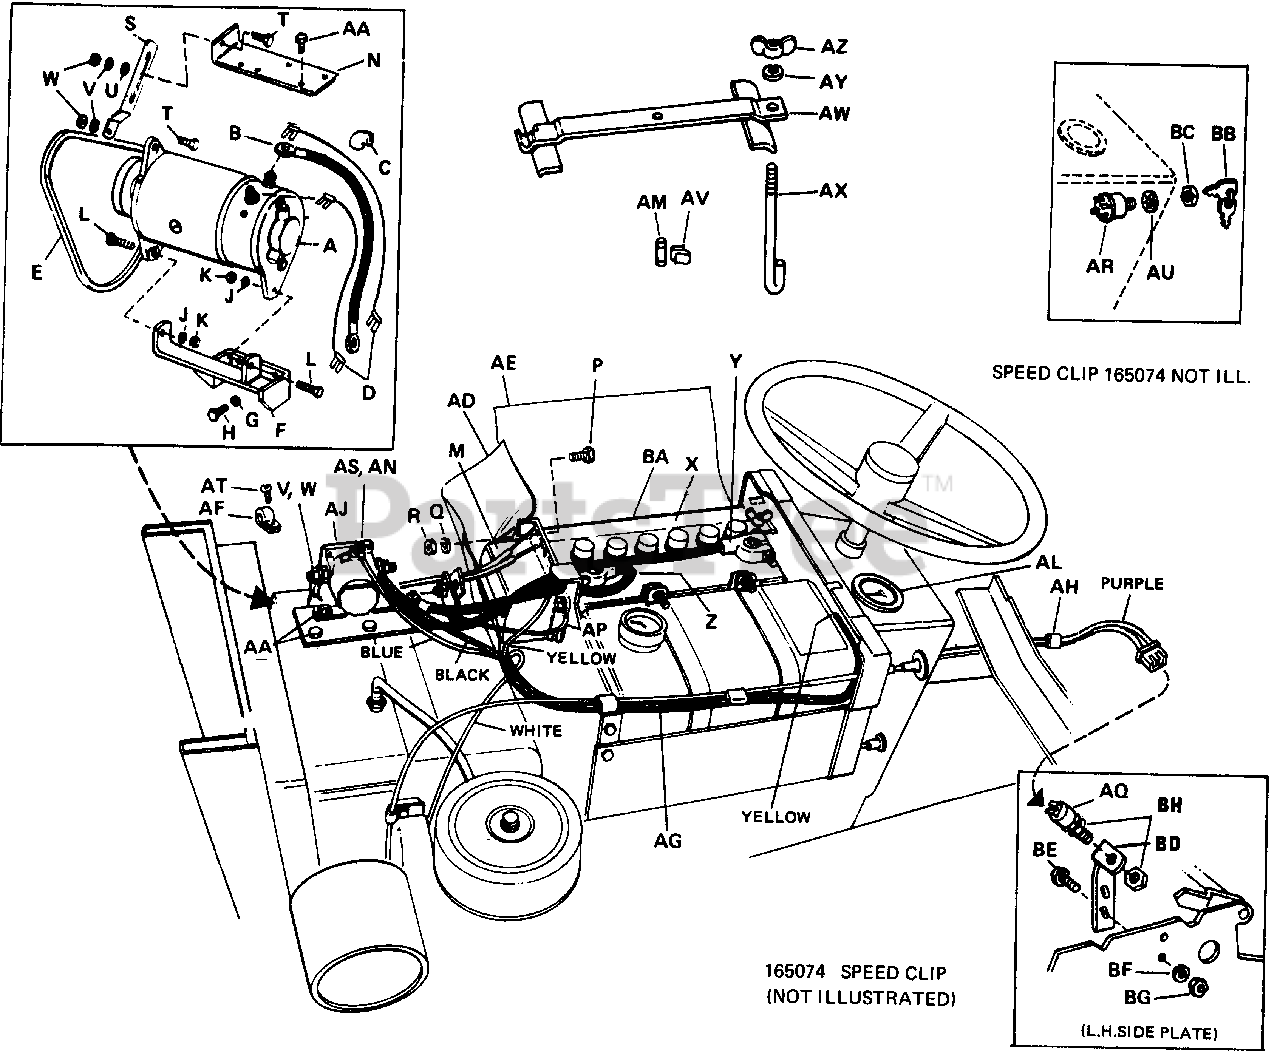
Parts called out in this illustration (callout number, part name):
A	Motor-Generator
B	Generator Start Cable
C	Terminal Cover
D	Reg. Gen. Wire
E	V-BELT, 39.12"
F	Support Assembly
G	Lock Washer, 5/16"
H	Hex. Cap Screw, 5/16"-18 x 3/4"
J	Lock Washer, 5/16"
K	Full Hex; Nut, 5/16"-18
L	Hex. Cap Screw, 5/16"-18 x 1 1/4"
M	Voltage Regulator
P	Hex. Cap Screw, 1/4"-20 x 3/4"
Q	Lock Washer, 1/4"
R	Full Hex. Nut, 1/4"-20
S	Belt Tightener
T	Hex. Cap Screw, 5/16"-18 x 3/4"
U	Plain Washer, 5/16"
V	Lock Washer, 5/16"
W	Full Hex. Nut, 5/16"-18
Y	Cable (Battery to Solenoid)
Z	Cable (Battery to Ground)
AA	Screw Hex. Thread Forming, 1/4"-20 x 1/2"
AD	Batter Insulation
AE	Fuel Tank Insulation
AF	Wire Clamp (Generator Cable)
AG	Harness Assembly
AL	Ammeter
AM	Fuse, 20 Amp
AN	Full Hex. Nut, 10-32
AP	Wire (Ground to Ground )
AQ	Safety Switch
AR	Starter Switch w/Keys
AS	Lock Washer, ext. No. 10
AT	Rd . Hd. Screw 10-24 x 1/2"
AU	Lock Washer Int. 9/16"
AV	Clip Fuse
AW	Battery Bracket
AY	Lock Washer, 1/4"
BA	Film, (SIMPLICITY)
BC	Hex. Nut, Special
BD	Switch Support
BE	Hex. Cap Screw, 5/16"-18 x 3/4"
BF	Lock Washer, 5/16"
BG	Full Hex. Nut, 5/16"-18
BH	Nut
